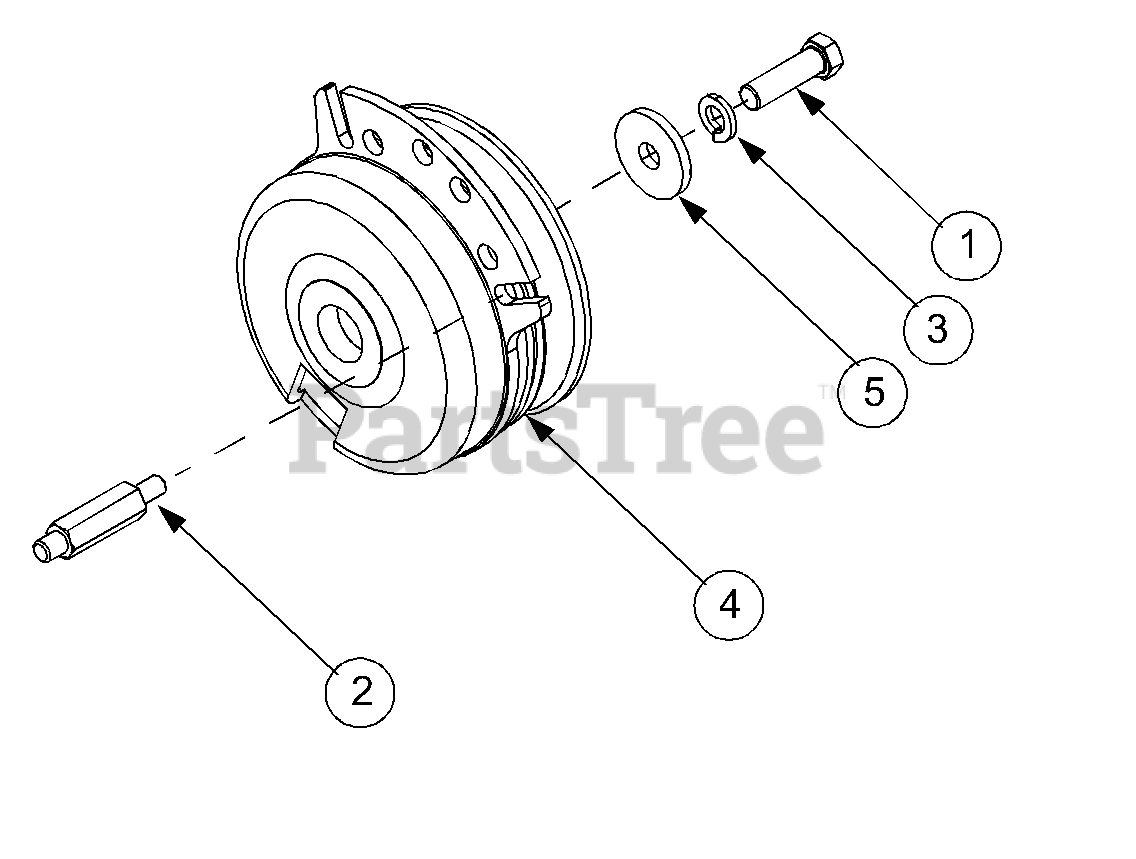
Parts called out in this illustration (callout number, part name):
1	Screw, Hex Cap, 7/16-20 x 1.5 GR5
2	Stud, Clutch Stop
3	Washer, Lock, 3/8
4	Clutch Assy, PTO
5	Washer, Flat, .445 x 1.5 x 1.72 Hdn
